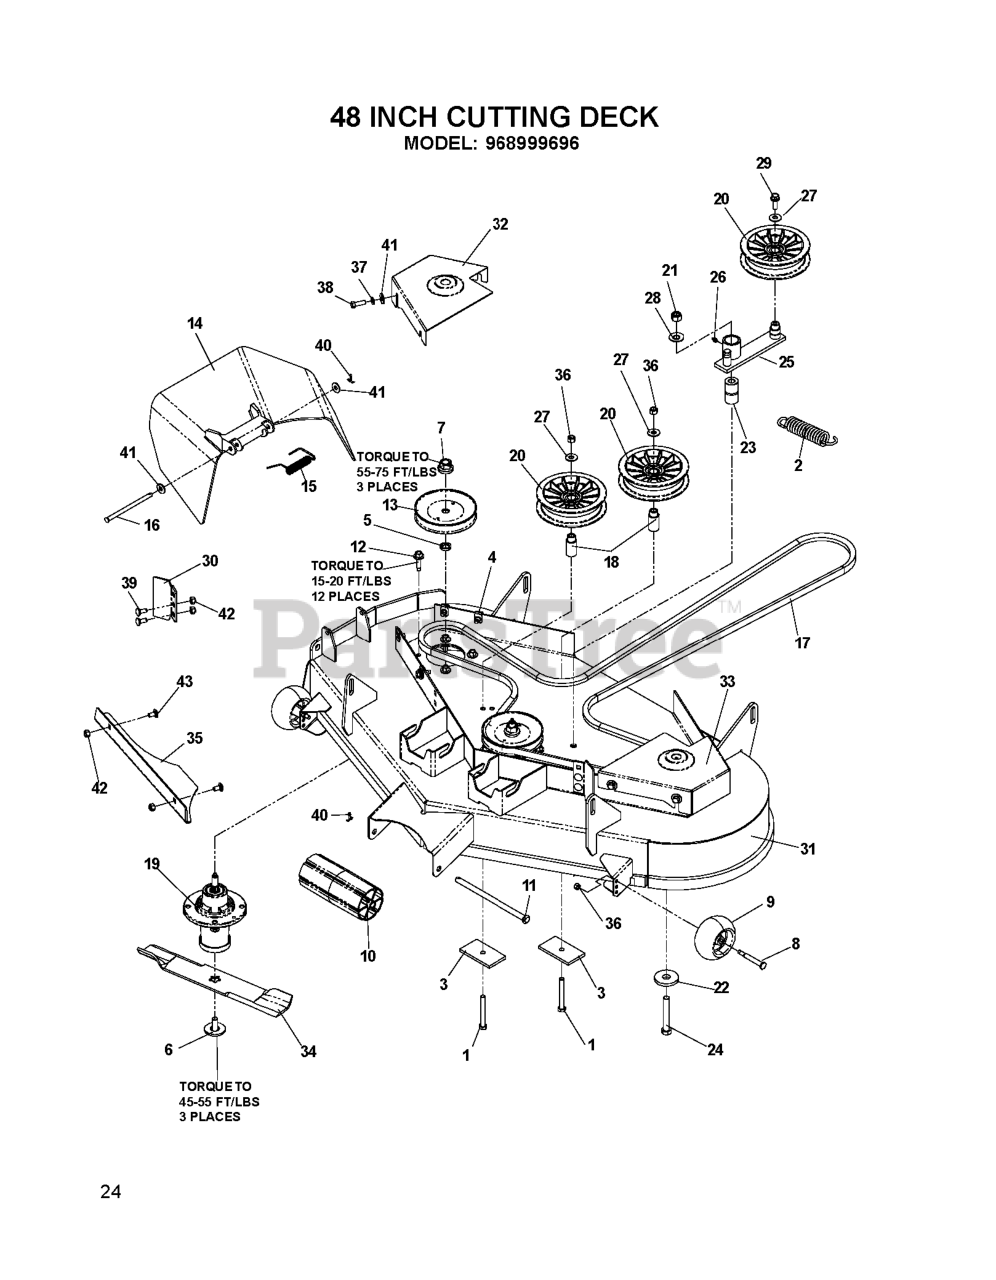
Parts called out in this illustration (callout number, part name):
1	HCS 3/8C X 3
3	SUPPORT PLATE
4	U-CLIP 5/16-18 NUT RETAINER
5	WASHER-SPACER
6	BLADE BOLT ASSY-7/16" TB REPL
7	LOCKNUT - 9/16
8	SHOULDER BOLT 1/2X2-5/8 ZD SPE
9	GAUGE WHEEL
10	NOSE ROLLER-48"
11	NOSE ROLLER ROD
12	WASHER HEAD SCREW
13	PULLEY MANDREL
14	DISCHARGE CHUTE 48"
15	SPRING - TORSION
16	PIN-CLEVIS 5/16 DIA X 5.19 ZD
17	DECK BELT
18	IDLER BUSHING
19	MANDREL.DECK.ASSEMBLY
20	IDLER
21	NUT 1/2-13 HEX NYLOC ZD
22	WASHER, SUPPORT
23	PIVOT BUSHING
24	HCS 1/2C X 3 1/4
26	ZERK
27	WASHER 3/8 FLAT
28	WASHER 1/2 FLAT
29	4CS 3/8C X 1 SERRATED HEAD
31	DECK W/DECALS 48"
32	BELT SHIELD W/DECALS 48 RT
33	BELT SHIELD W/DECALS 48 LT
34	BLADE, 16-1/4"
35	CONFINEMENT PLATE 48" BLK
36	NUT 3/8-16 NYLOC
37	WASHER.LOCK.HVY.HLCL.SPR.5/16
38	HCS 5/16C X 1
39	BOLT 5/16C X 3/4" CARRIAGE
40	RP_COTTER PIN 1/8 X 3/4
41	WASHER 5/16 FLAT
42	NUT 5/16 NYLOC
43	CARRIAGE BOLT 5/16C X 5/8"
